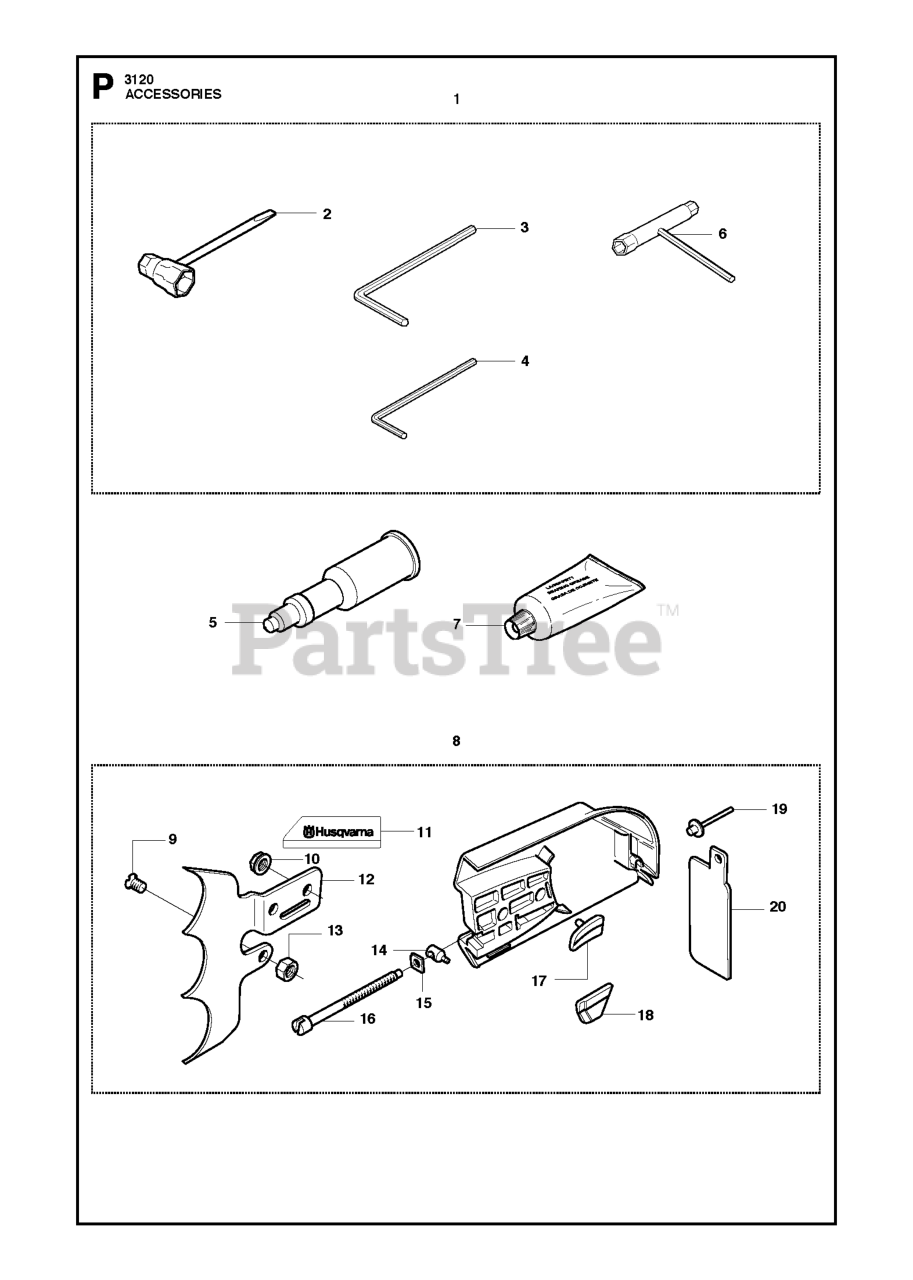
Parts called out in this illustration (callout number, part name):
2	COMBI TOOL
3	L-SPANNER
4	L-SPANNER
5	Grease Gun
6	COMB.TOOL 8-10-14
7	GREASE
8	CLUTCH CVR 3120K ONLY NO CHNBR
9	SCREW MF6S 6X14
10	NUT M8 FLANGE
12	FELLING DOG
14	PULLER UNIT
17	CHAIN GUIDE
18	CHAIN GUIDE
20	DUST GUARD
